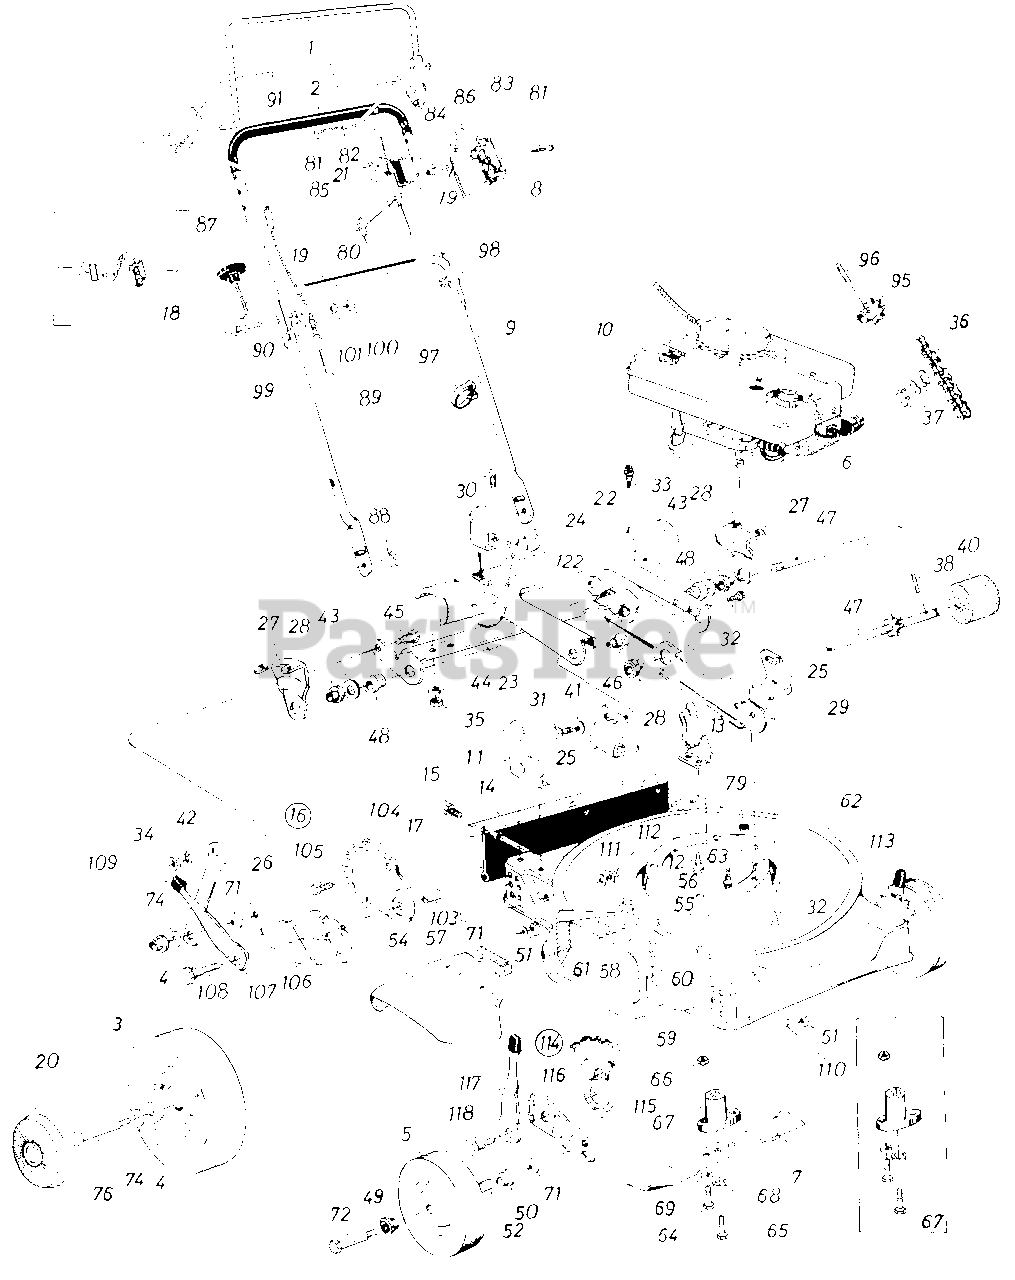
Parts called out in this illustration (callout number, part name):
1	Control Handle Ass'y. L.H.
3	Rear Wheel Ass'y. Comp. 9 x 1.75
4	Flange Brg. 1/2" I.D.
5	Front Wheel Ass'y. Comp.
6	Spark Plug Boot
7	Blade 22"
8	Throttle Wire 53.0"
9	Lower Handle
11	Handle Brk't. Ass'y. R.H.
12	Hex Wash. Hd. B '-Tap Scr. 5/16-18 x .50" Lg.
13	Handle Brk't. Ass'y. L.H.
14	Retainer Strip
15	Hex AB-Tap Scr. 1/4 x .62" Lg.
16	R.H. Height Adj. Comp.
17	Rear Flap Ass'y.
18	Kit Control Housing Comp.
19	Control Labels
20	Hub Cap
21	Flat Wash. .203" I.D. x .406" O.D.
22	Pinion Pivot Cover 22"
23	Cam
24	Engagement Arm
25	Pivot Brk't.
26	Link
27	Axle Brk't.
28	Flanged Ball Brg. .500" I.D.
29	Brg. Support
30	Carriage Bolt 1/4-20 x .50" Lg.*
31	Hex Bolt 3/8-16 x .50" Lg.*
32	Hex "B"-Tap Scr. 1/4" x .38" Lg.
33	Hex Wash. Hd. "AB"-Tap Scr. 1/4" x .62" Lg.
34	Hex Nut 5/16-18 Thd.*
35	Hex Nut 1/4-20 Thd.*
36	#48 Chain 1/2" Pitch 49 Links
37	#48 Master Link
38	Spring Pin Spir. 3/16" Dia. x 1.25" Lg.
40	Drive Pinion
41	Bell-Wash. .400" I.D. x .88" O.D. x .060
42	L-Wash. 5/16" I.D.*
43	Fl-Wash. .531" I.D. x .930" O.D. x .050
44	L-Wash. 1/4" I.D.*
45	Shld. Bolt .437" Dia. x .162
46	Shld. Nut .625" Dia. x .162
47	Pinion Shaft w/7 Tooth Sprocket
48	Flange Brg. .506" I.D.
49	Bearing 3/8" I.D.
50	Bearing 1/2" I.D.
51	Hex Nut 3/8-16 Thd.*
52	Spacer
54	Chute Deflector Ass'y. Com p.
55	Pivot Pin
56	Cap Speed Nut 1/4" Rod
57	Torsion Spring
58	Hex Bolt 1/4-20 x .50" Lg.
59	Hex Nut 1/4-20 Thd.
60	L-Wash. 1/4" I.D.
61	Hinge Plate
62	22" Deck Ass'y.
63	Hex Wash. Hd. TT-Tap Scr. 3/8-16 x 1.0" Lg.
64	Hex Bolt 5/16-24 x 1.00" Lg. Grade 5
65	Hex Bolt 3/8-24 x 2.25" Lg.
66	Hex Nut 5/16-24 Thd.
67	Blade Adapter Kit
68	L-Wash. 3/8 I.D. H.D.
69	L-Wash. 5/16" I.D.
71	Bell-Wash. .400" I.D. x .88" O.D.
72	Front Axle Bolt
74	Fl-Wash. .531" I.D. x .93" O.D.
76	Rear Axle Bolt
80	Control Cable 39.0"
81	Truss Mach. Self-Tap Scr. #12 x 1.50" Lg.
82	Spacer.23" I.D.
83	Control Panel Half
84	Control Disc Pin
85	Clutch Panel Half
86	Throttle Control Lever
87	Upper Handle
88	Hairpin Cotter
89	Clutch Cable w/Spring
90	Cable Mtg. Brk't.
91	Drive Control Handle
95	10 Tooth Sprocket Ass'y.
96	Spiral Pin 3116" Dia. x 1.00"
97	Cable Tie
98	Curved Hd. Carriage Bolt 5/16-18 x 1.38" Lg.
99	Rope Guide Bolt
100	Hex Nut 5/16-18 Thd.
101	L-Wash. 5/16" I.D.
103	Spacer.395" I.D. x .503" O.D. x .562" Lg.
104	Index Plate
105	Hex Bolt 3/8-16 x .75" Lg.
106	Pivot Bar R.H.
107	Spring Lever
108	Shoulder Bolt .500" Dia. x 3.75" Lg.
109	Spring Lever Knob
110	Bell-Wash. .39 I.D. x 1.4 O.D.
111	Bell-Wash. .336" I.D. x .860 O.D.
112	Hex L-Nut 5/16-18 Thd.
113	Height Adj. Ass'y. Comp. L.H .
114	Height Adj. Ass'y. Comp. R.H.
115	Height Adj. Plate
116	Pivot Bar
117	Spring Lever Ass'y. w/Knob
118	Shoulder Bolt .500" Dia. x .375" Lg.
122	Compression Spring .47" O.D. x 1.93" L.g.
